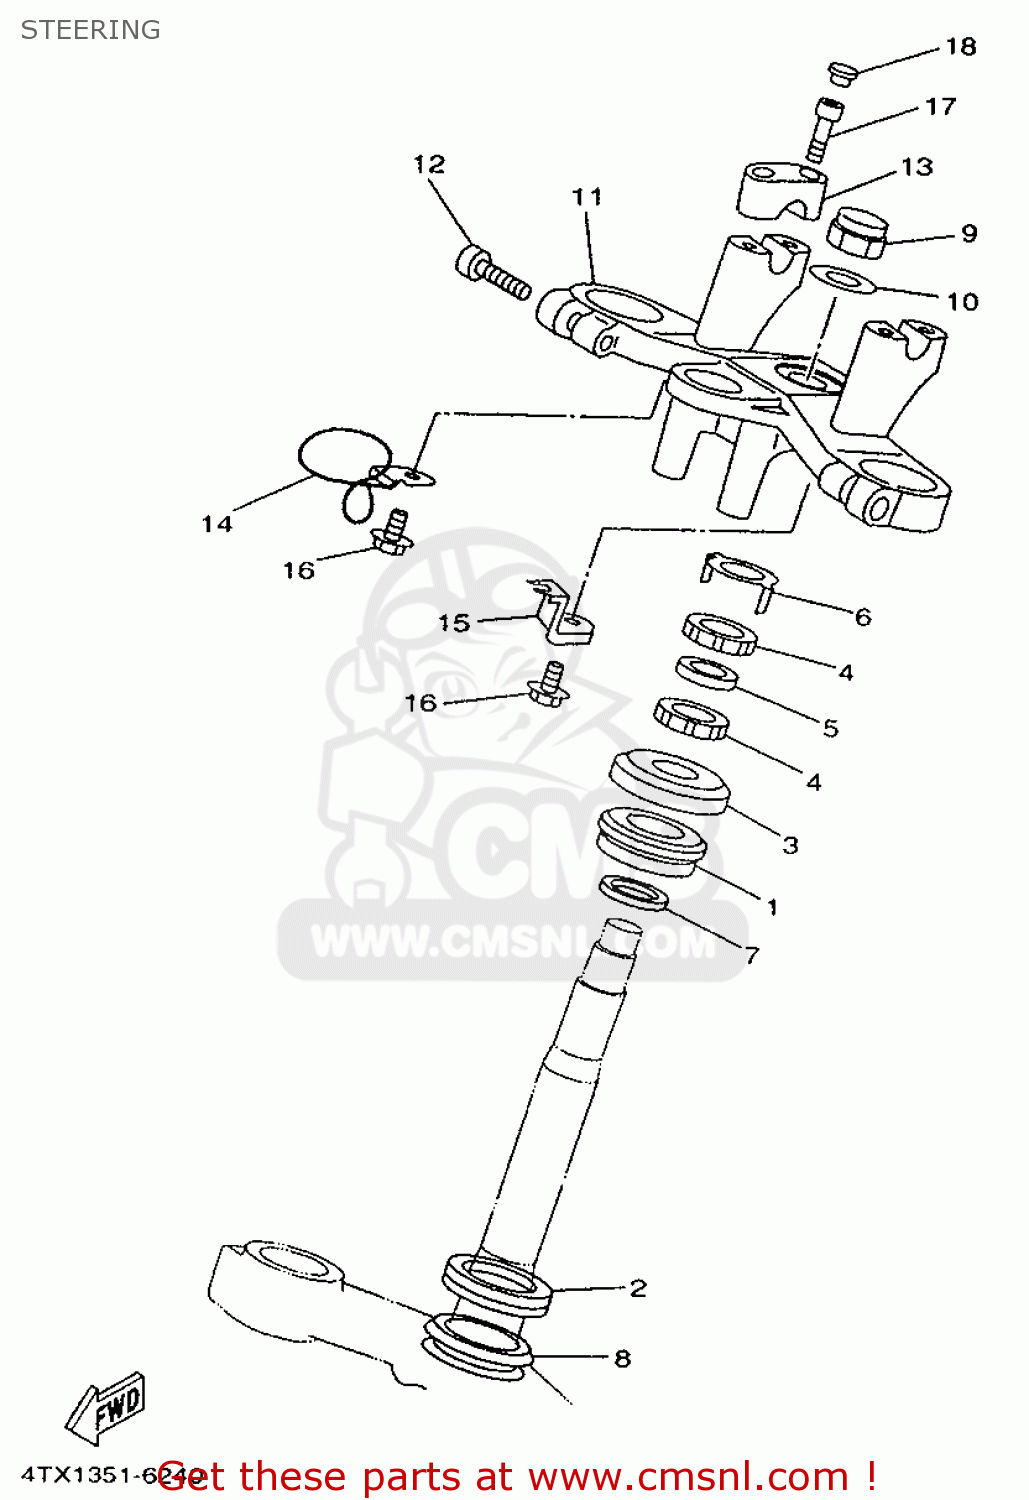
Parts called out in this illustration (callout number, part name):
01	BEARING(3FV)
02	BEARING(3FV)
03	COVER, BALL RACE 2
04	NUT 1372345400
05	WASHER, PLATE (26H)
06	WASHER, SPECIAL
07	WASHER, PLATE(3FV)
08	SEAL, STEERING
09	NUT, CROWN(4FM)
10	WASHER, PLATE(4FM)
11	CROWN, HANDLE
12	BOLT,SOCKET
13	HOLDER, HANDLE UPPER
14	GUIDE, CABLE
15	HOLDER, WIRE
16	BOLT, FLANGE
17	BOLT,SOCKET
18	PLUG(42X)
